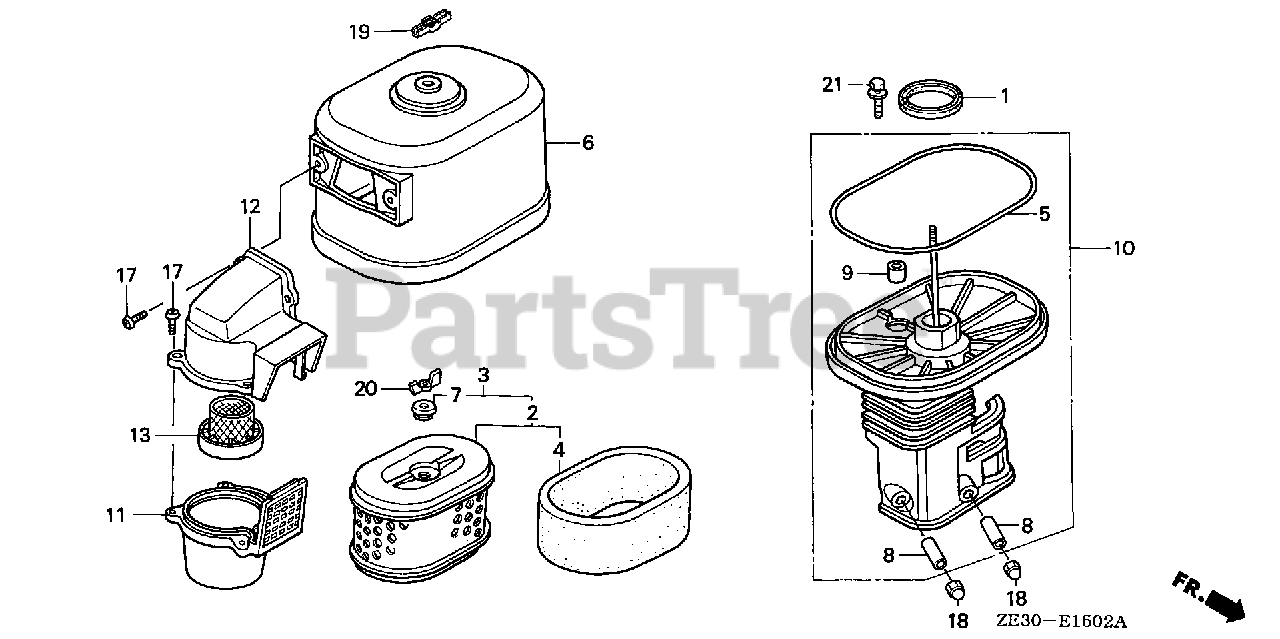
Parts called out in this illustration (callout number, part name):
1	GASKET, ELBOW
2	ELEMENT, AIR CLEANER
3	ELEMENT, AIR CLEANER
4	FILTER (OUTER)
5	SEAL, AIR CLEANER COVER
6	COVER, AIR CLEANER (CYCLONE)
7	GROMMET, AIR CLEANER
8	COLLAR, AIR CLEANER
9	COLLAR B, AIR CLEANER
10	ELBOW, AIR CLEANER
11	CASE, PRE AIR CLEANER
12	CAP, PRE AIR CLEANER
13	GUIDE, PRE AIR CLEANER
17	SCREW, PAN (5X16.5)
18	NUT, CAP (6MM)
19	NUT, AIR CLEANER COVER (DACRO COATING)
20	NUT, TOOL BOX SETTING
21	BOLT-WASHER (6X20)
